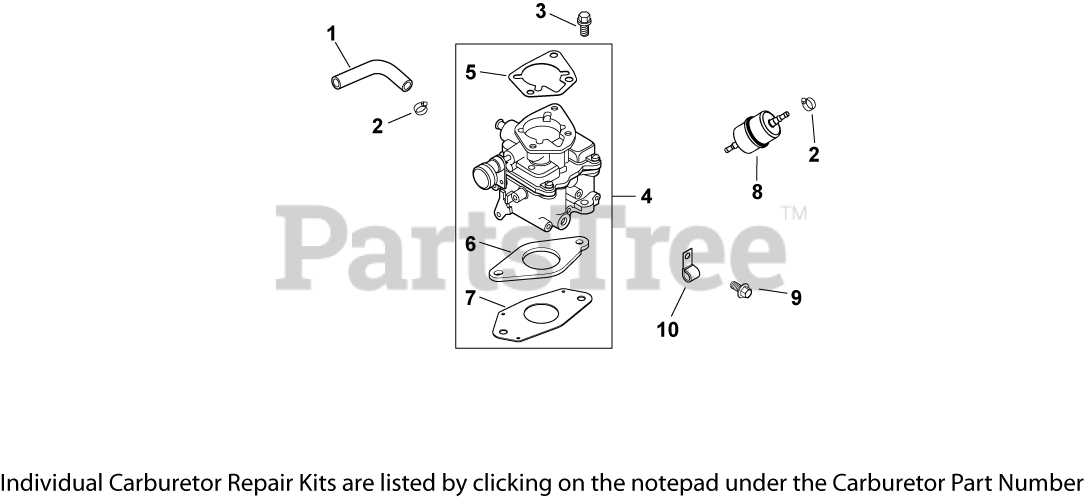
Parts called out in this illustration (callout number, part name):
1	HOSE,LW PERM.FUEL 24.00"-USE 25 111 81-S
2	CLAMP, HOSE (KM)-USE 25 237 31-S
3	SCREW, FLG M6X1.0X25
4	KIT, CARBURETOR W/GASKETS
5	GASKET, AIR CLEANER BASE
6	GASKET, CARBURETOR
7	GASKET, CARBURETOR
8	FILTER, FUEL
9	SCREW, FLG M6X1.0X12
10	CLIP, CABLE
